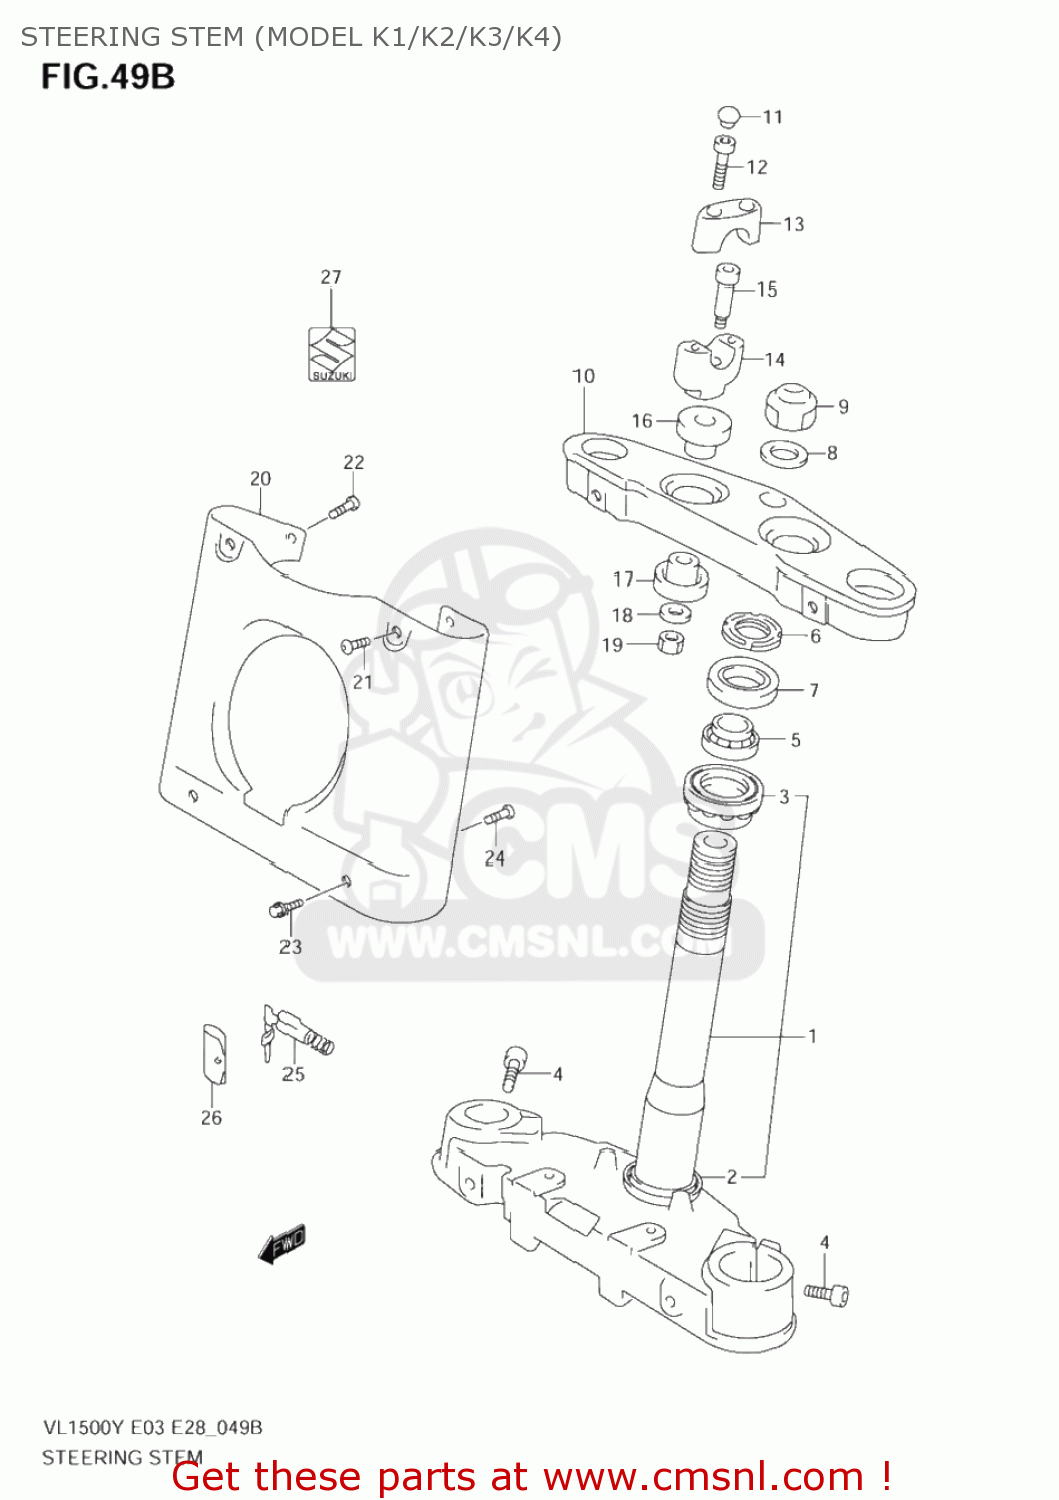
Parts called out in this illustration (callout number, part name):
1	BRACKET,FR FORK UNDER
2	SEAL,STEERING LWR
3	BEARING(30X55X17)
4	BOLT,STEM
5	BEARING(25X47X15)
6	NUT,STEERING STEM(25X44X10)
7	DUST SEAL,STEERING UPR
8	WASHER(22.5X32X1.6)
9	NUT,CAP
10	HEAD,STEERING STEM
11	CAP(OD:14.5)
12	BOLT
13	HOLDER,HANDLE UPR
14	HOLDER,HANDLE UNDER
15	BOLT
16	DAMPER,RUBBER
17	CUSHION,RUBBER UNDER
18	WASHER
19	NUT
20	COVER,FR FORK UPR
21	SCREW(8X16)
22	SCREW(6X12)
23	BOLT
24	SCREW(6X12)
25	LOCK SET,STEERING
26	CASE,STEERING KEY
27	EMBLEM,S
